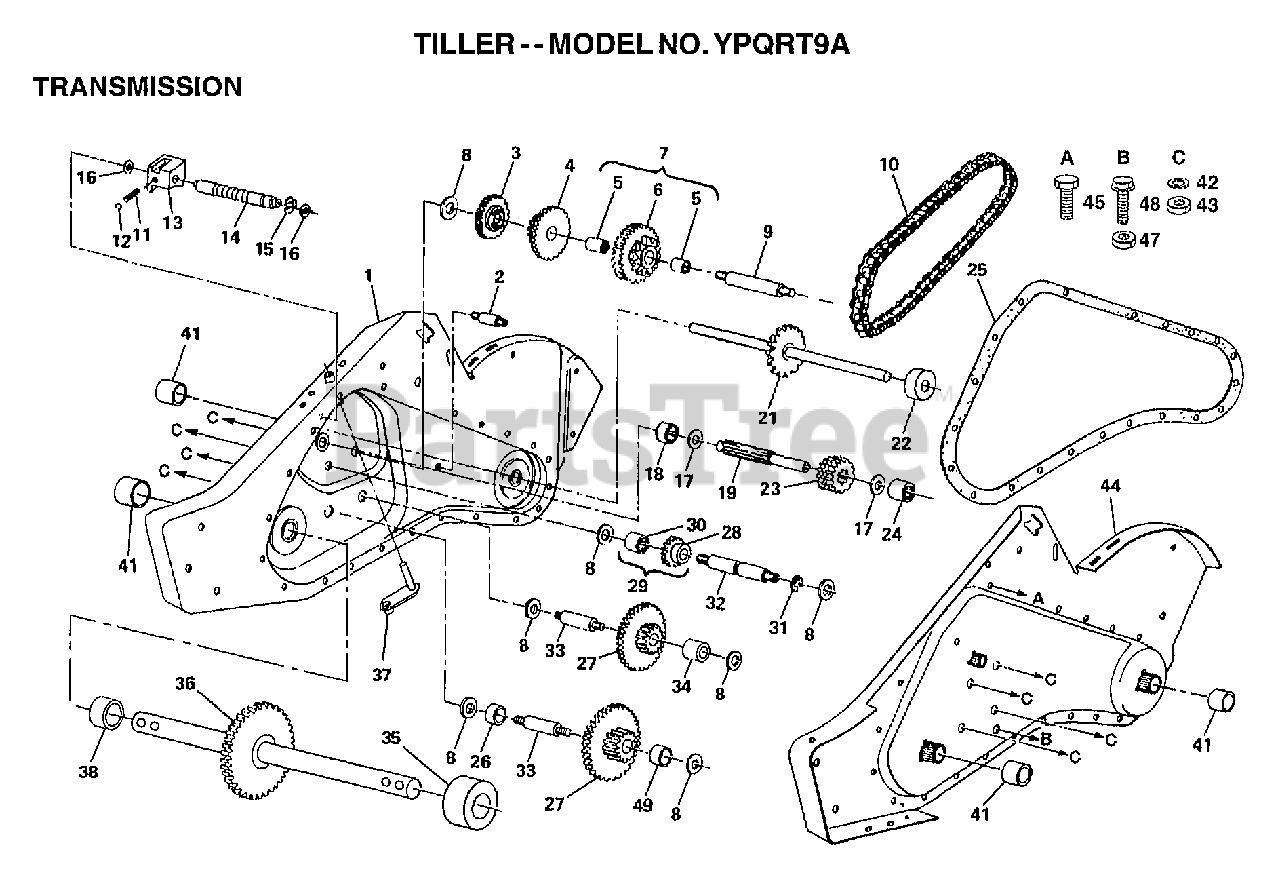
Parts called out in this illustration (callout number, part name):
2	BOLT TI
3	REVERSE GEAR TI
4	CLUSTER GEAR TI
5	"CRT, BEARING"
7	SPROCKET ASSY TI
8	WASHER
9	REDUCTION SHFT TI
10	CHAIN TI
11	SPRING-SHIFT CRT
13	SHIFT FORK TI
14	SHIFT SHAFT TI
15	KLIP RING
16	WASHER SEAL
17	"T, BEARING"
18	"TI, BEARING"
19	SHAFT INPUT
21	SHAFT TINE CRT
22	SPACER CRT
23	INPUT PINION TI
24	NEEDLE BRNG LT
25	GASKET.GEARCASE
26	SPACER CRT
27	GEAR CLUSTER CRT
28	REVERSE GEAR TI
29	GEAR ASSY TI
30	NEEDLE BEARING TI
31	KLIP RING
32	REVERSE SHAFT TI
33	SHAFT CRT
34	SPACER CRT
35	SPACER CRT
36	SHAFT ASSY CRT
37	BRACKET ASM SHIFT
38	SPACER CRT
41	SEAL ASM-OIL
42	LOCKWASHER
43	NUT.ASF.HEX.7/16
44	"GEARCASE ASSY,LH"
45	SCREW 5/16-18X5/8
47	NUT.HEX.5/16-18
48	BOLT TI
49	SPACER CRT
